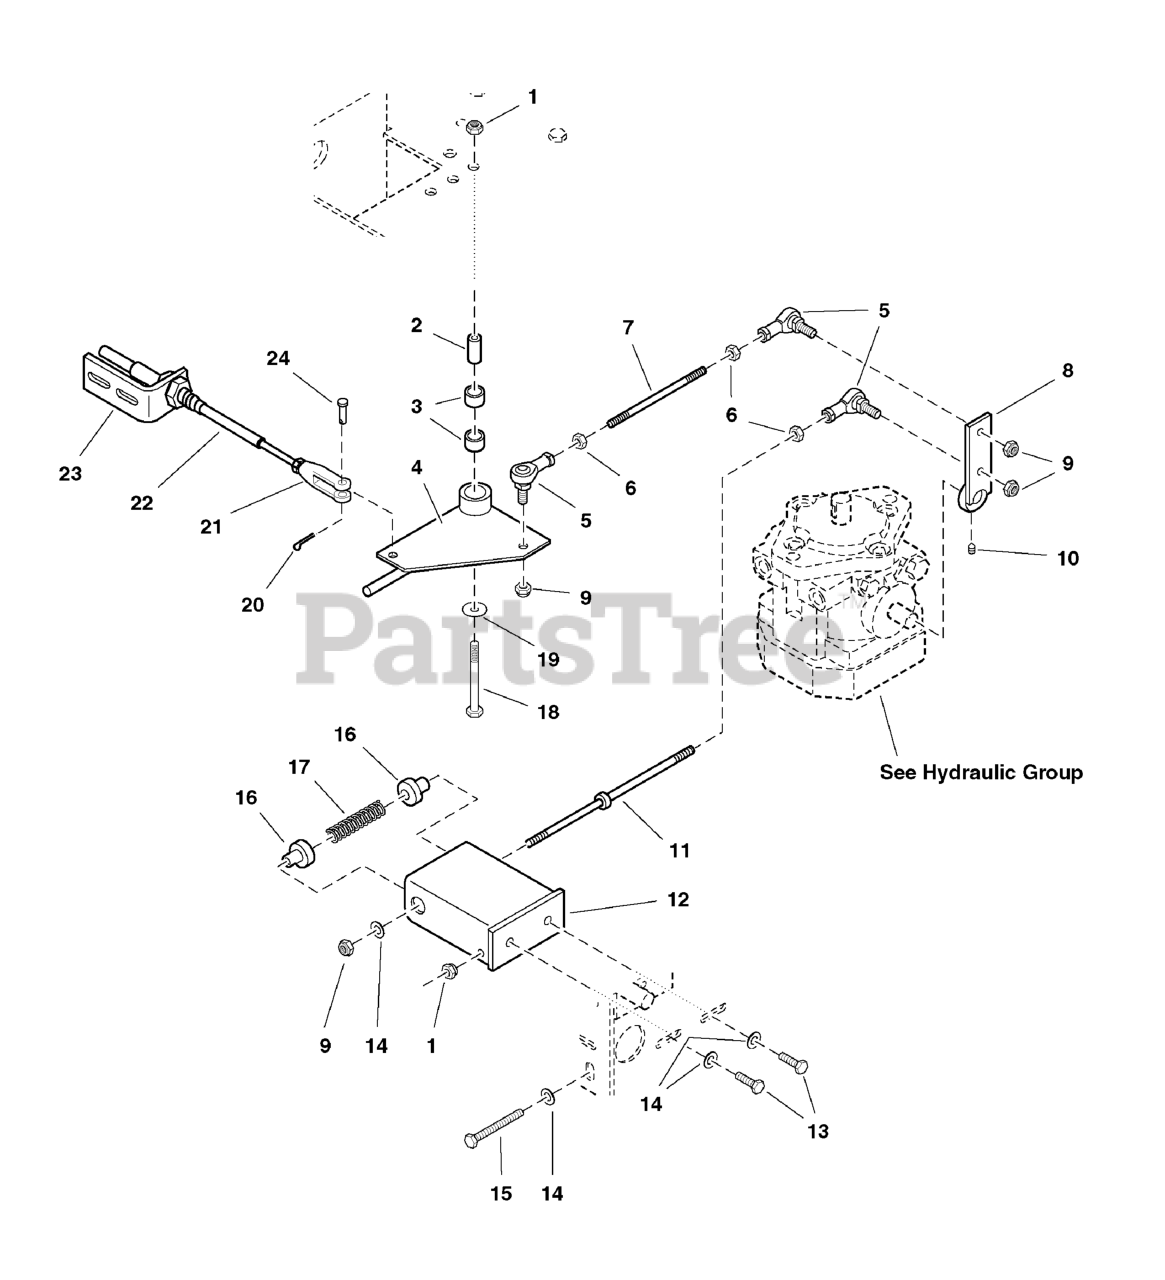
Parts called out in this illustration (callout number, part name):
1	NUT, 5/16-18 Hex Nylon Lock
2	SPACER, .33 X .75 X 1.56
3	BUSHING, Brass
4	SPEED CONTROL PIVOT, Complete
5	BALL JOINT 5/16-24 LH FEMALE W/STUD, BR
6	NUT, 5/16-24 Hex
7	CONTROL ROD
8	LEVER, Pump Control
9	NUT, 5/16-24 HEX NYLON LOCK
10	SET SCREW, 5/16-18 x 1/2, Cone
11	SPRING RETURN ROD
12	BOX, Spring Mount
13	BOLT, 5/16-18 X 1 GD5 YZ
14	WASHER, 5/16" SAE
15	BOLT, 5/16-18 x 3-1/2 TFL
16	GUIDE, Spring Return
17	SPRING, Compression
18	BOLT, 5/16-18 x 2-1/4
19	WASHER, 5/16" Fender
20	COTTER PIN, 1/16" x 1/2"
22	CABLE, Speed Control
23	CABLE BRACKET
24	CLEVIS PIN, 1/4 x 1
